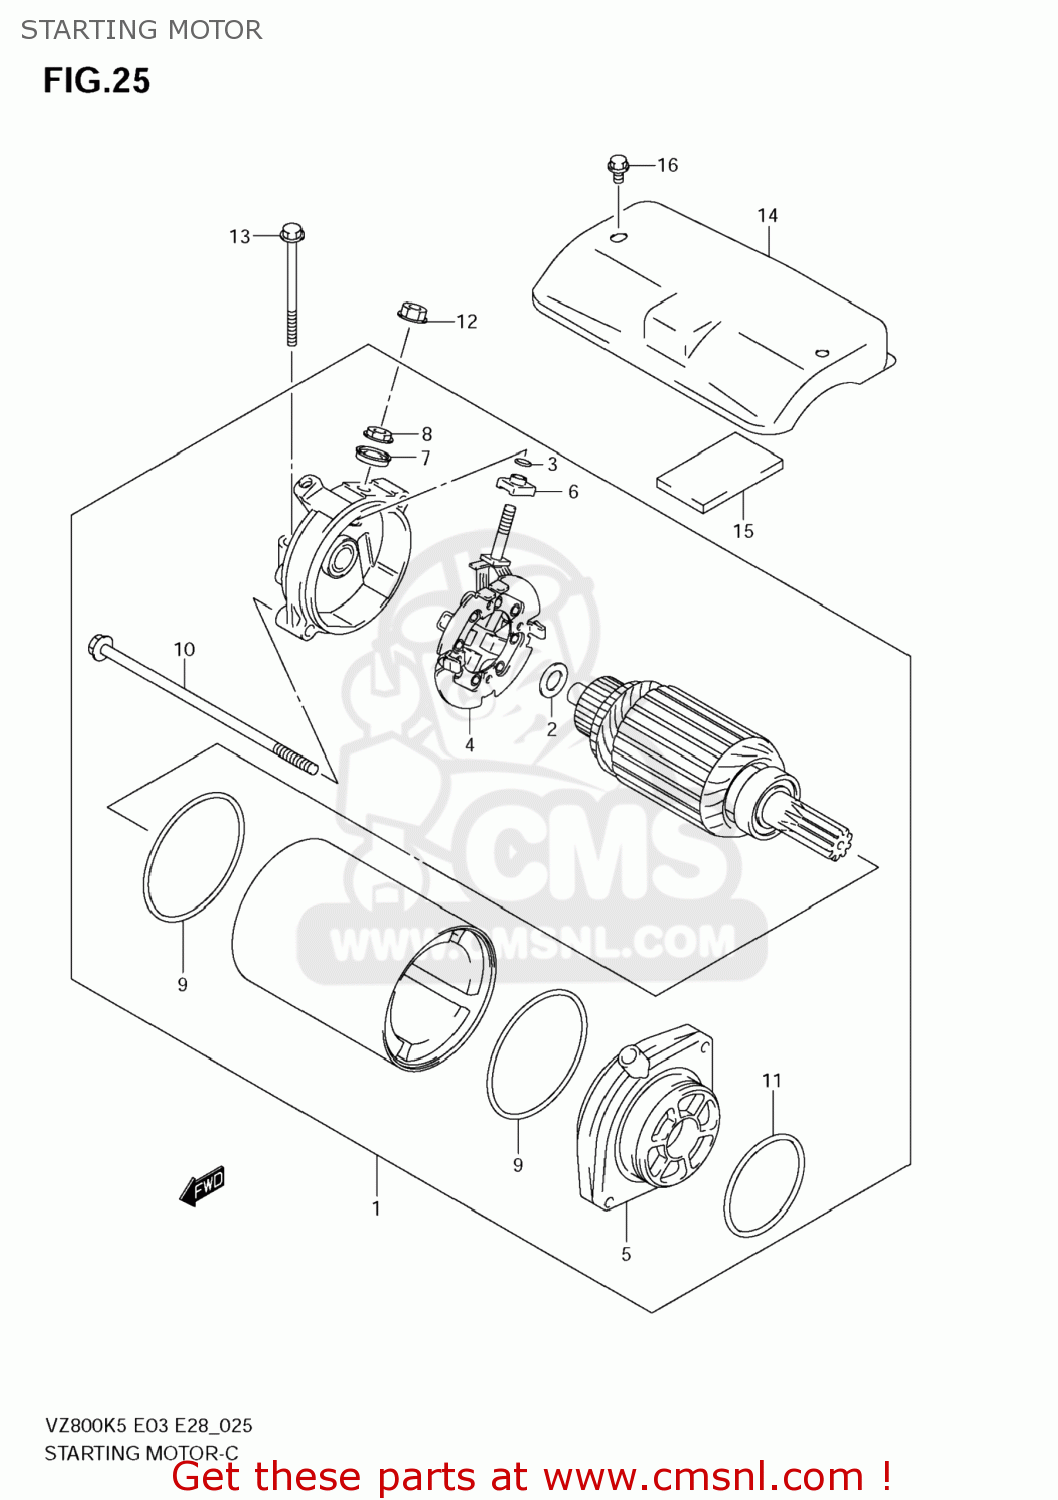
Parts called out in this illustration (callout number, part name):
1	MOTOR ASSY,STARTING
2	SHIM SET,STARTING MOTOR
3	O RING
4	HOLDER SET,BRUSH
5	BRACKET SET
6	BUSHING
7	BUSHING
8	NUT
9	O RING
10	BOLT
11	O RING
12	NUT
13	BOLT(6X60)
14	COVER,STARTING MOTOR
15	DAMPER,MOTOR COVER
16	BOLT
